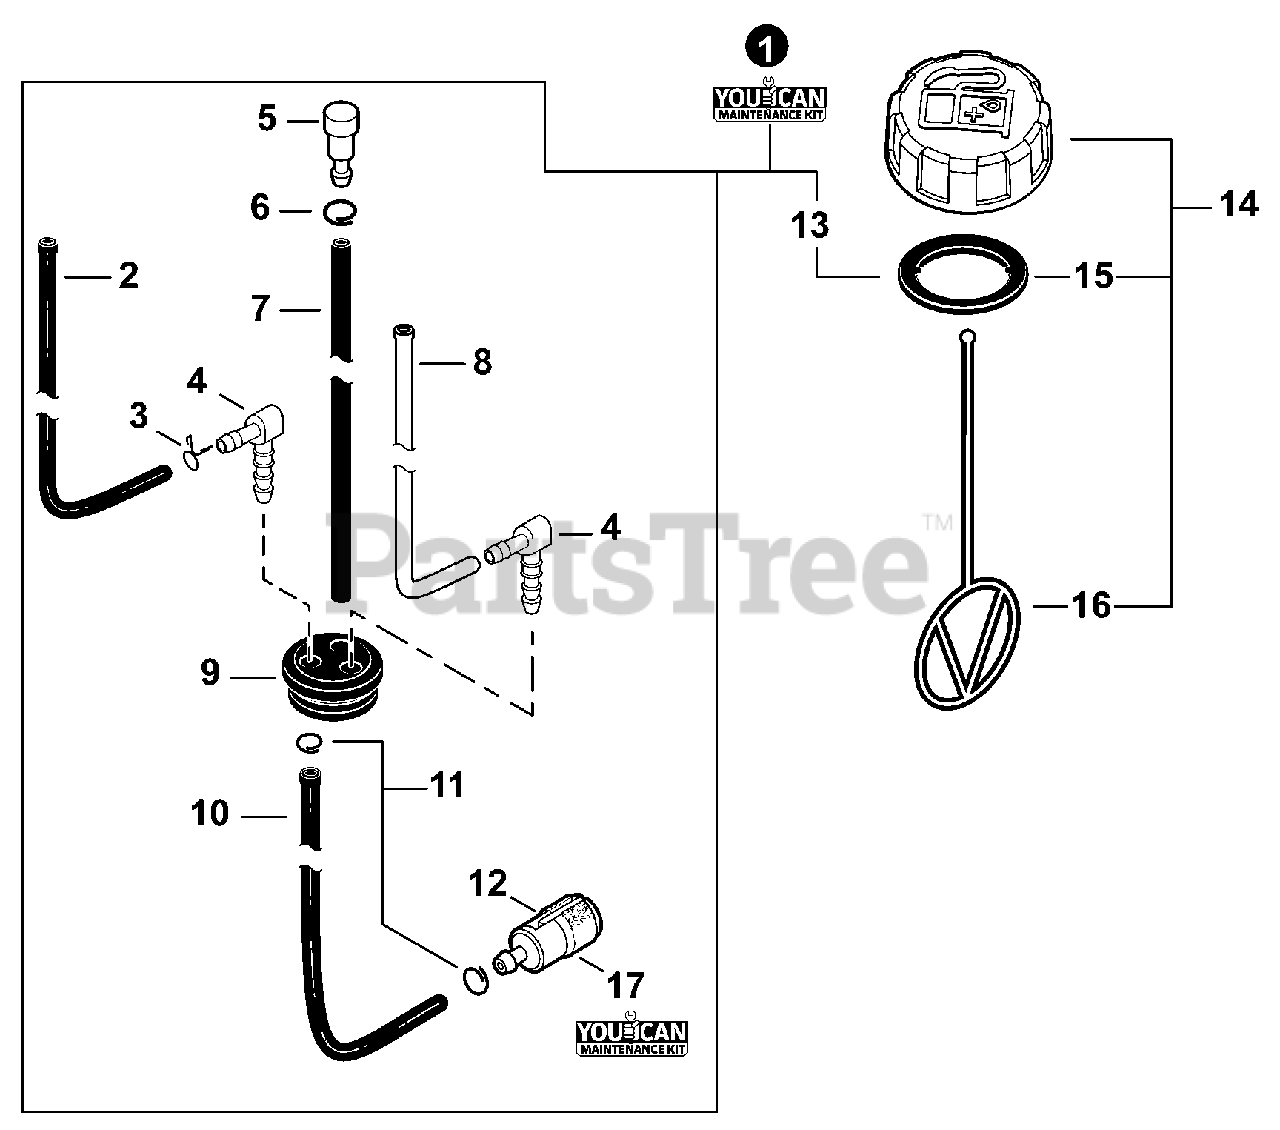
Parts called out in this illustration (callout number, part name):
1	FUEL SYSTEM KIT - YOUCANT
2	PIPE, FUEL 3×5×87 BLACK
3	CLIP, SPRING Ø5.2
4	CONNECTOR, PIPE
5	VENT ASSY
6	CLIP Ø6.5 MM
7	PIPE 3×6×115 BLACK
8	PIPE, FUEL 3×6×80 CLEAR
9	GROMMET, FUEL
10	PIPE, FUEL - 3×5×125 - BLACK
11	CLIP Ø6
12	FILTER, FUEL
13	GASKET, FUEL CAP
14	CAP ASSY, FUEL
15	GASKET, FUEL CAP
16	CONNECTOR, CAP L= 100 MM
17	TUNE-UP KIT - YOUCANT
